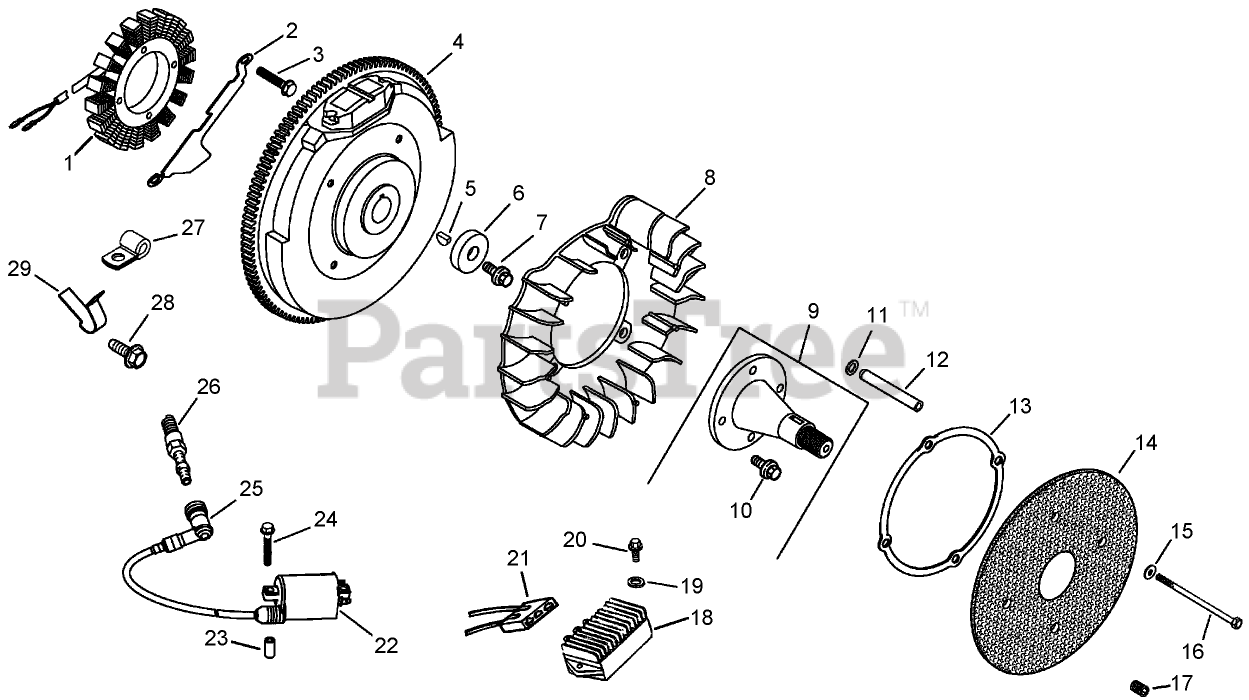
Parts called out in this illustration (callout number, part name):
1	Stator Kit (Includes 3, 21)
2	Bracket-Wire, Stator
3	Screw-Tapping
4	Flywheel
5	KEY (3/16 X 5/8)
6	WASHER-FLAT (13/32)
7	SCREW-FLANGE (M10X1.5X45)
8	Fan
9	Front Drive Shaft Kit (Includes 10)
10	Screw-HF (M8x1.25x25)
11	Washer-Spring (10MM)
12	Spacer
13	Ring-Support
14	Screen-Grass
15	WASHER-FLAT (1/4)
16	Screw-HH (M6x1.0x100)
17	Screw-Set (10-24X.25)
18	Rectifier-regulator
19	WASHER-FLAT (.188)
20	SCREW-PHL HD (11-16X.88)
21	Connector (3 contact)
22	Coil-Ignition
23	Spacer
24	Screw-Tapping
25	Spark Plug Boot ASM
26	SPARK PLUG (PRO SERIES)
27	CLAMP-INSULATED
28	SCREW-FLANGE, THREAD FORMING (M5X0.8X16)
29	Clamp-Hose
